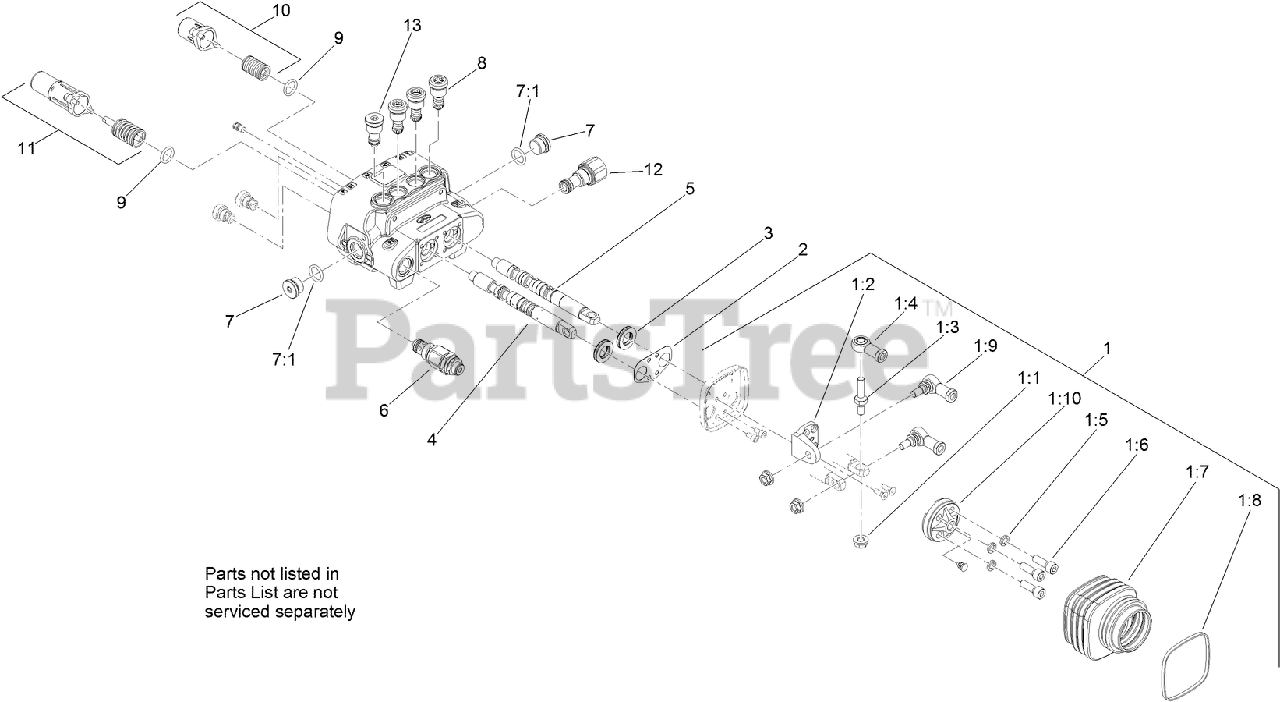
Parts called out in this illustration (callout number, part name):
1	JOYSTICK KIT
1:2	PIVOT-JOYSTICK
1:3	PIN-JOYSTICK
1:4	END-ROD
1:6	SCREW-HSH
1:7	BELLOW-RUBBER
1:8	TIE-CABLE
1:9	JOINT-JOYSTICK
1:10	HOLDER-ARTICULATED
2	SEAL-JOYSTICK
3	SEAL-VALVE, SPOOL
4	SPOOL - VALVE
5	SPOOL-VALVE
6	VALVE-RELIEF, MAIN
7	PLUG-HEX
7:1	O-RING
8	VALVE-RELIEF
9	SEAL-VALVE
10	VALVE SPRING KIT
11	DETENT SPRING KIT
12	JOINT-SAE 8
